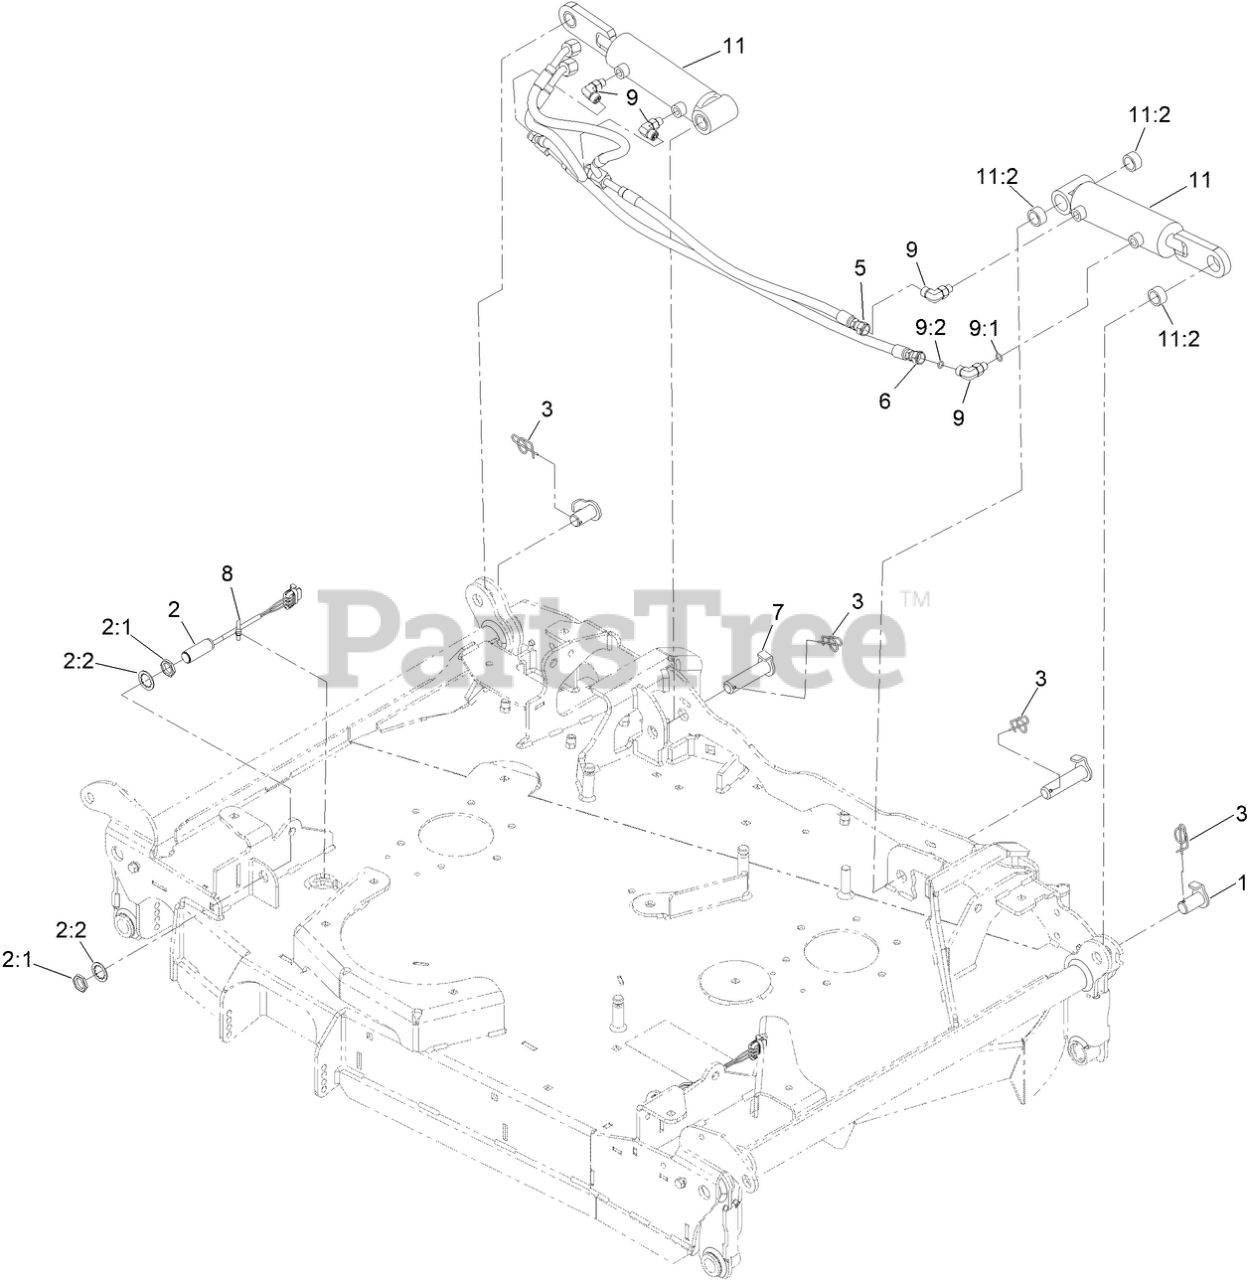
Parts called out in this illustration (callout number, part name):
1	PIN-CYLINDER
2	PROXIMITY SWITCH ASM
2:1	NUT-HEX
2:2	WASHER-LOCK, INTERNAL TOOTH
3	PIN-LOCKING COTTER
5	HOSE ASM
6	HOSE ASM
7	ASM-CYL PIN BASE
8	TIE-CABLE
9	FITTING-ELBOW, 90 DEG
9:1	O-RING
9:2	O-RING
11	CYL-DECK FOLD
11:2	BUSHING-0.75X1.00X0.50 LONG
